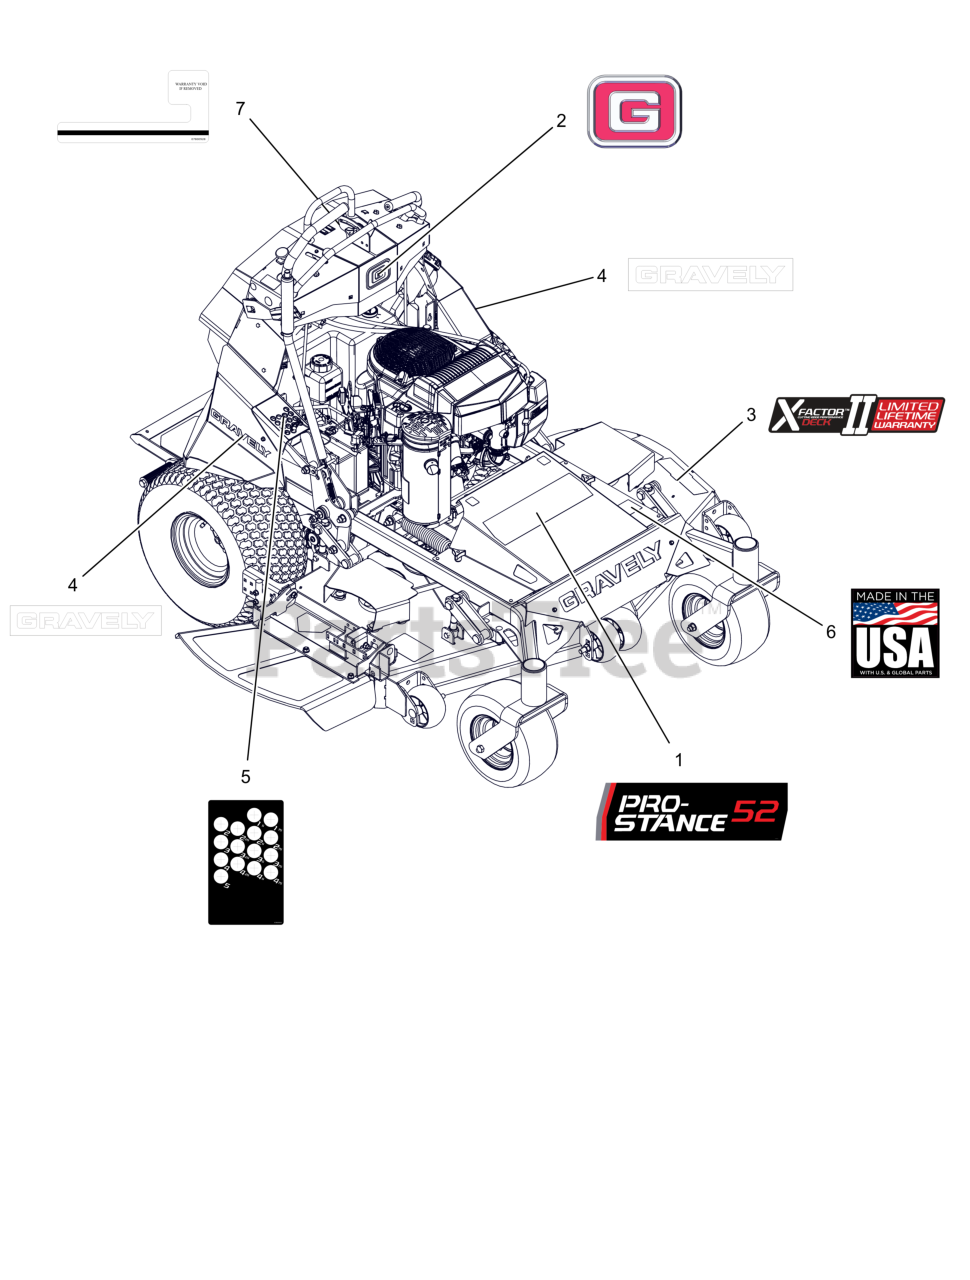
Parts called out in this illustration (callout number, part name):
1	DECAL, PROSTANCE 52
2	DECAL, GRAVELY BRAND
3	DECAL, X-FACTOR DECK
4	DECAL, 9.5" GRAVELY LOGO
5	DECAL, DECK - HEIGHT ADJUST
6	DECAL, MADE IN USA
7	DECAL,HOURMETER - SECURITY
